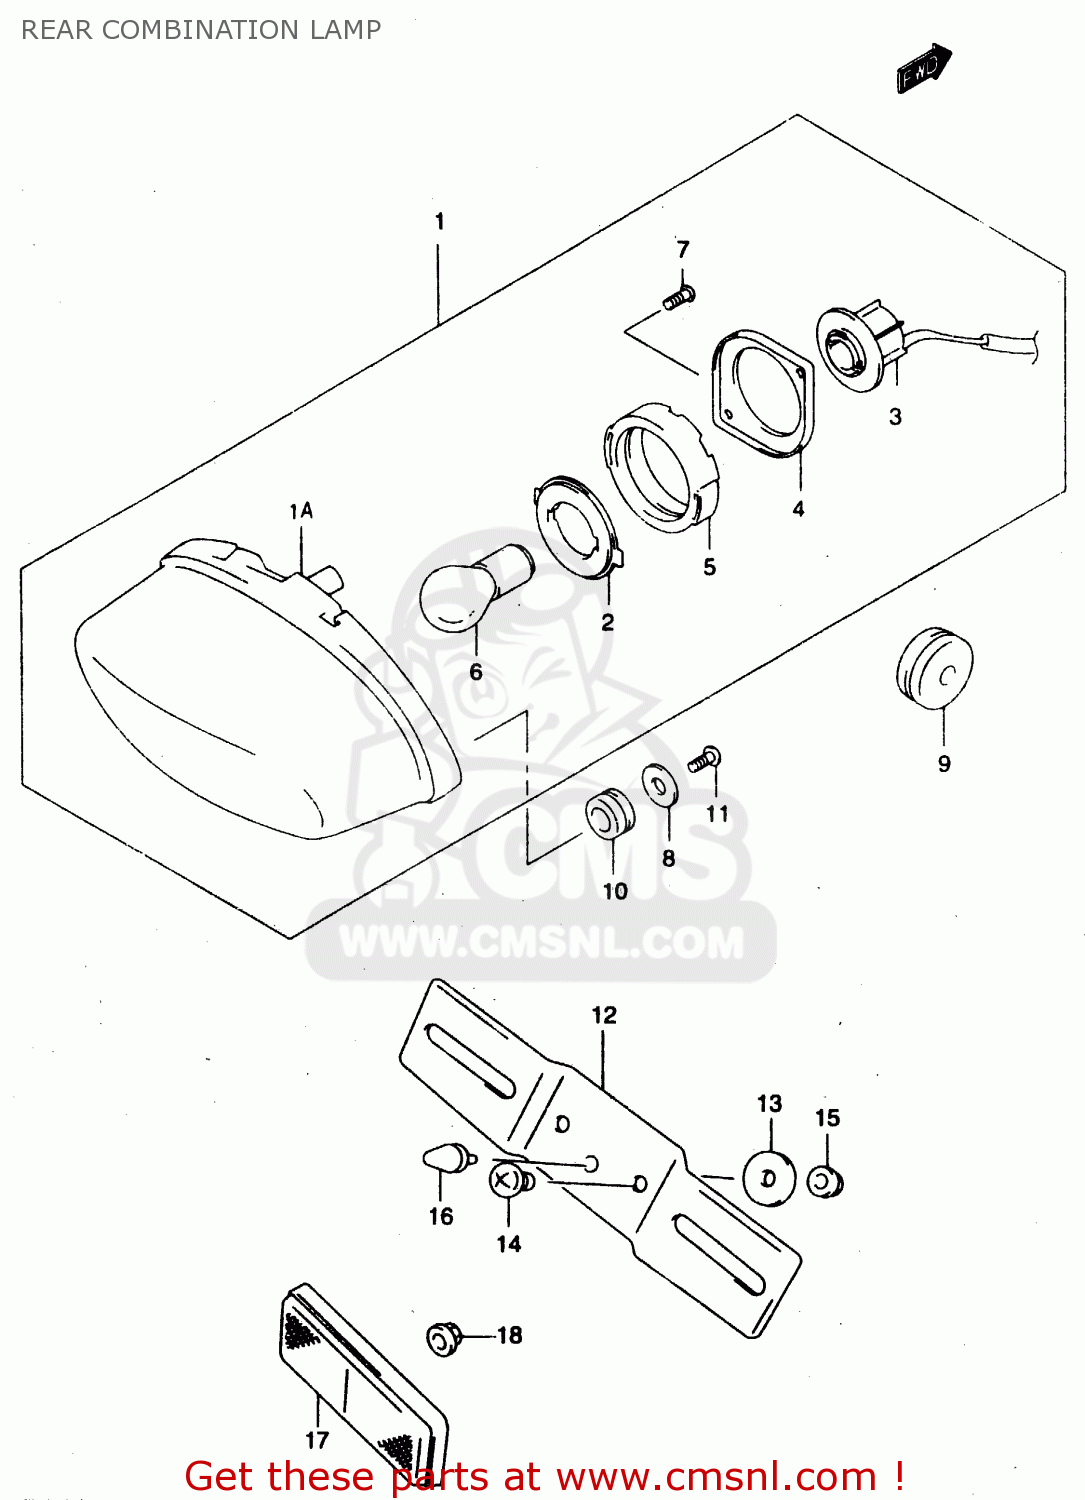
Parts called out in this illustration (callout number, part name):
1	LAMP ASSY,RR COMBINATION
1A	LAMP UNIT
2	PLATE NO.1
3	SOCKET & CORD
4	PLATE NO.2
5	CUSHION
6	BULB(12V21/5W)
7	SCREW
8	WASHER(5.5X20X1.2)
9	GROMMET
10	CUSHION
11	SCREW
12	PLATE,RR LICENSE
13	WASHER(6.5X20X1.6)
14	SCREW 6X12
15	NUT
16	CUSHION
17	REFLECTOR ASSEMBLY,REAR
18	NUT
